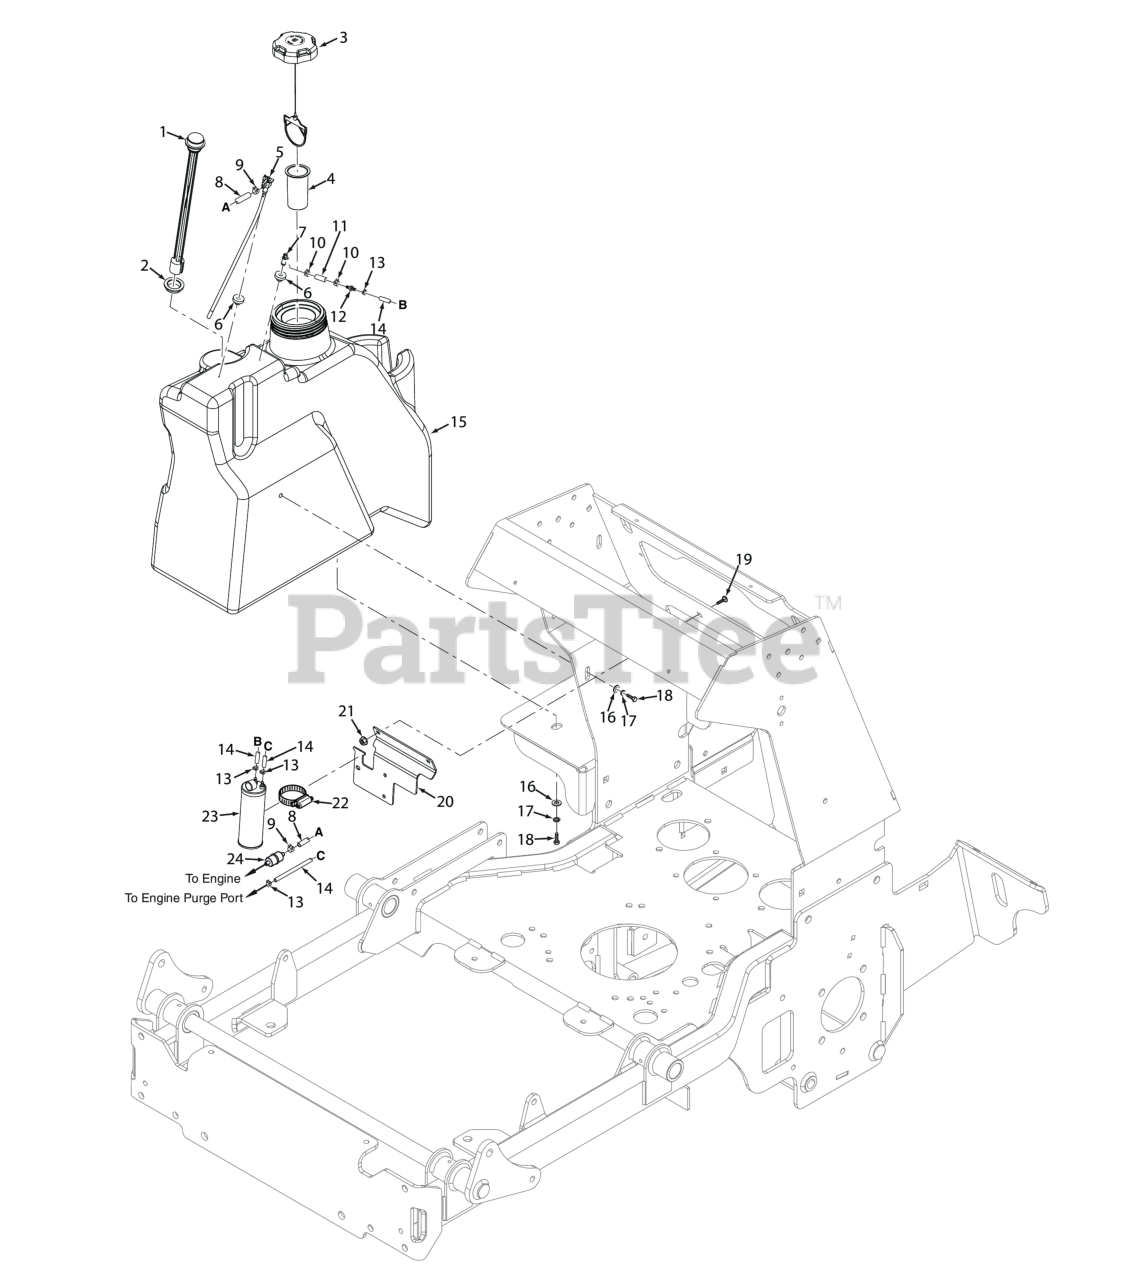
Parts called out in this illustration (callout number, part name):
1	Fuel Gauge Assy., 14.6" (32)
2	Grommet, Fuel Gauge
3	Fuel Cap w/ Tether (E.P.A.)
4	Tube, Fuel Tank Insert - 4"
5	Valve, Fuel Shutoff (32)
6	Bushing, 0.56" Dia. Viton
7	Remote Vent
8	Fuel Hose, 1/4" I.D. Non-Perm (791DFI Fuel Return) - Order by Inch
9	Clamp, Fuel Hose 1/4" Hose I.D.
10	CLAMP, FUEL HOSE(KAWASAKI ONLY)
11	Hose, 1/4" Vapor Recovery (order by inch)
12	Mender, 1/4 x 3/16 w/0.02 Hole
13	Clamp, Vapor Recovery Hose 3/16"
14	Hose, Vapor Recovery 3/16" (order by inch)
15	Fuel Tank Assy., SVRII-32
16	Flatwasher, 5/16-.375 x .875 x .083 (35BV & 37BV-EFI)
17	Lockwasher, 5/16 (.317 x .586 x .078) Helical Spring
18	BOLT, SERRATED FLANGE HEX HEAD 5/16-18 X 3/4"
19	Bolt, 5/16-18 x .75 RHSN Carriage
20	Bracket, Hydro Tank Mounting
21	Nut, Serrated Flange 5/16-18 (Right Front Engine Mounting, Briggs and Kohler Only)
22	Clamp, 3-1/2" Max. Dia.
23	Carbon Canister - SVR-52V / SVR-61V
24	Fuel Filter
